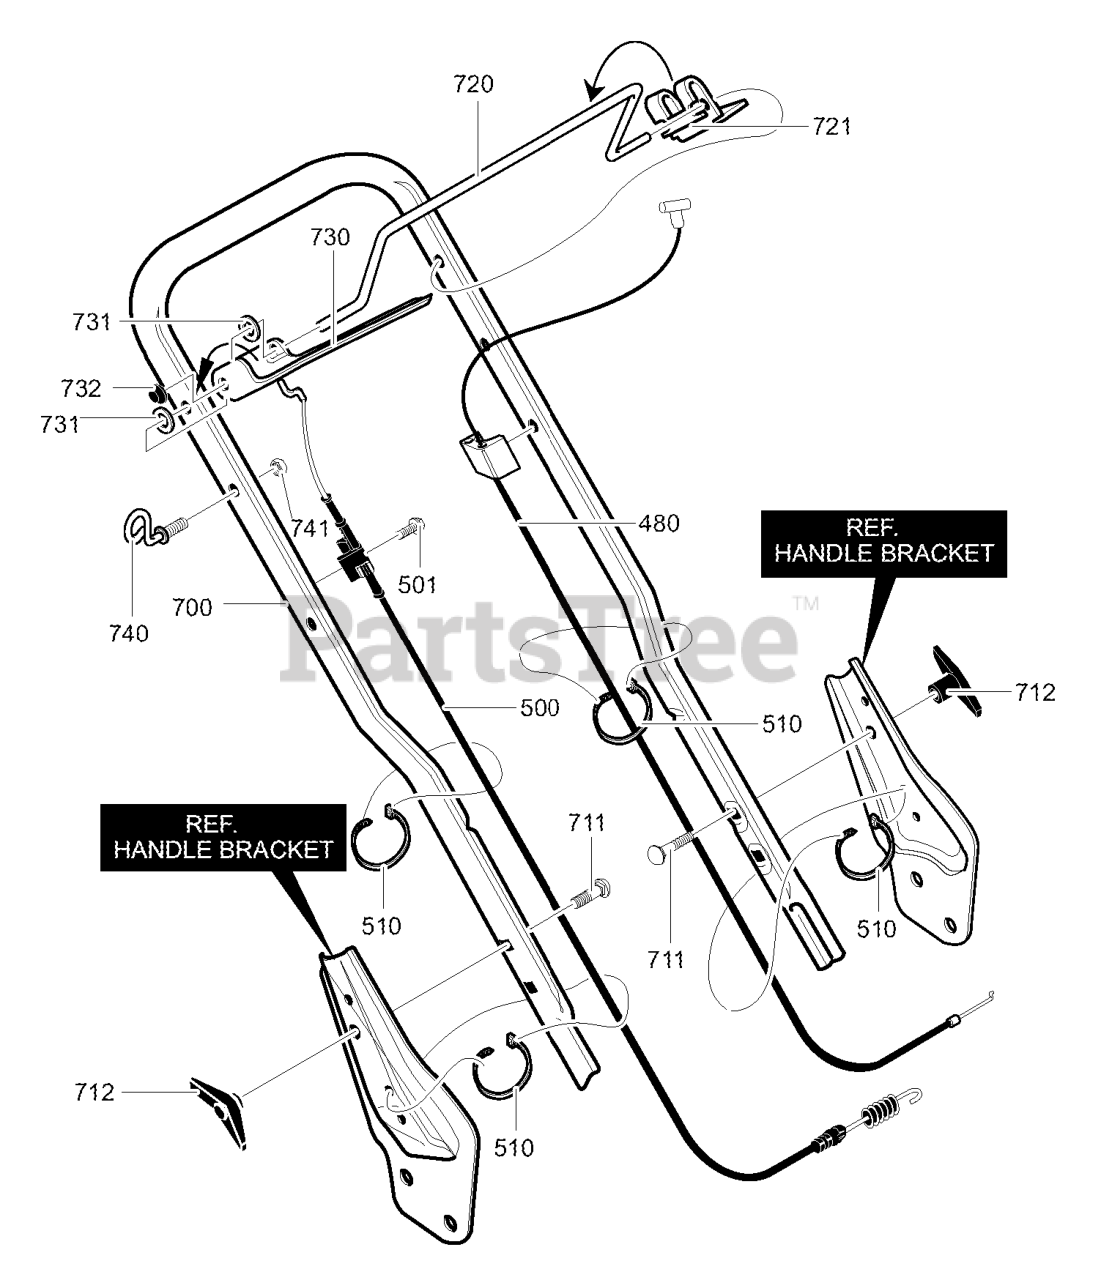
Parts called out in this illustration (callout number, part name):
480	CABLE, STOP
500	CABLE, DRIVE 21
501	SCREW, 10-16X.75
510	CABLE TIE
711	CARR. BOLT, 5/16-18X2.00
712	WING KNOB
720	STOP LEVER
721	BRACKET, STOP LEVER
730	LEVER, DRIVE CONTROL
731	WASHER, NYLON
732	CAP, PUSH ON
740	ROPE GUIDE 1/4-20
741	NUT, 1/4-20
